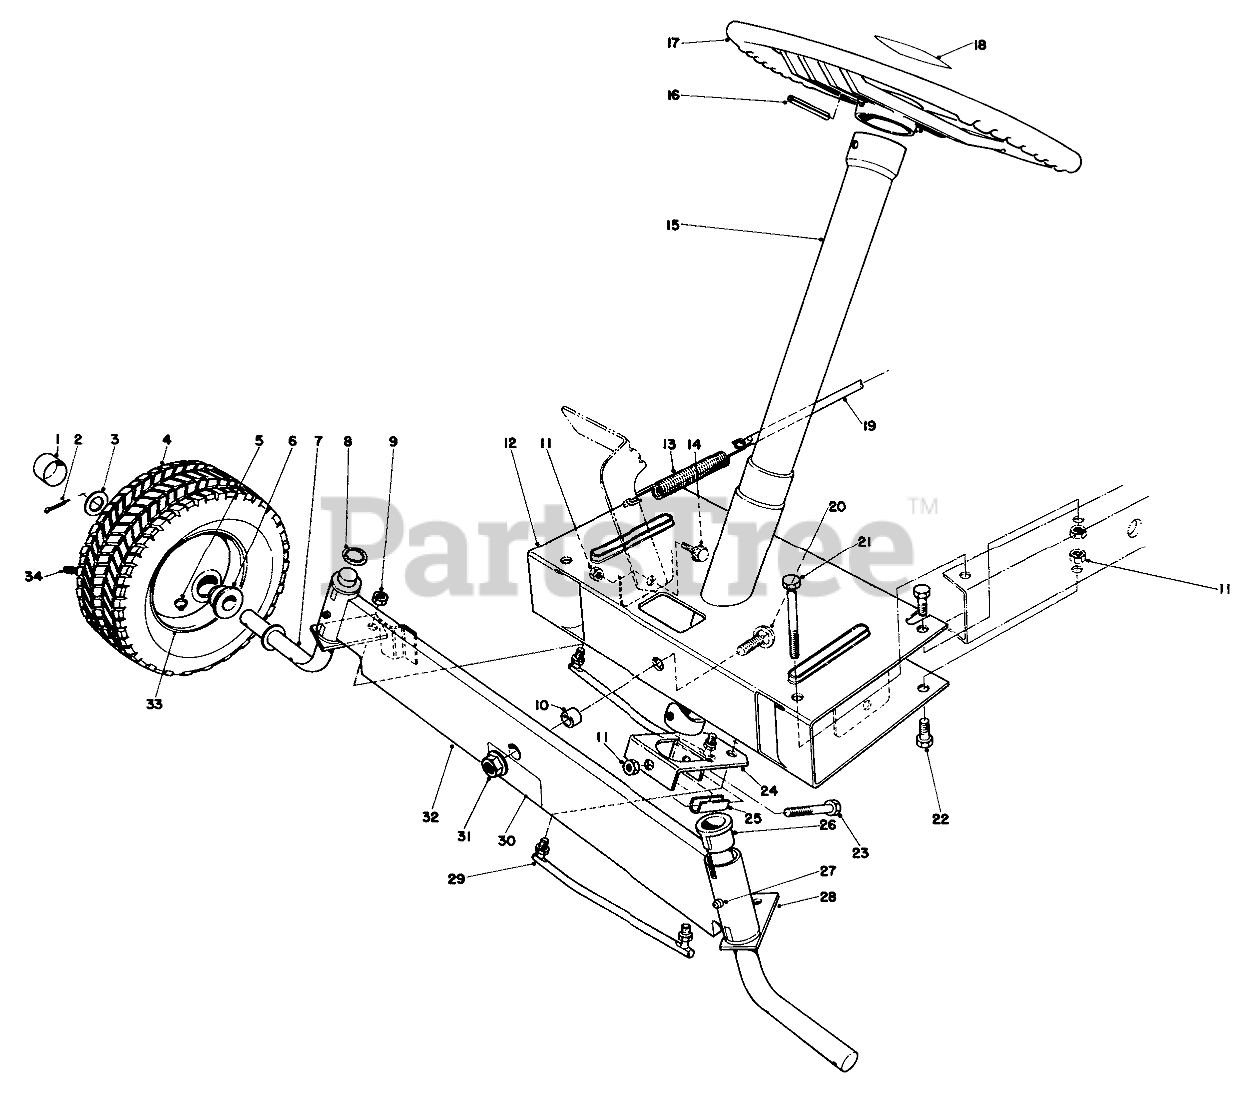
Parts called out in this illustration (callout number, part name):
1	Hub Cap
2	PIN-COTTER
3	WASHER-FLAT
4	Tire Turf King
5	FITTING-GREASE
6	BUSHING
7	SPINDLE WA RH
8	RING-RETAINING
10	FRONT AXLE SPACER
11	NUT-LOCK, CONE
12	Front Frame
13	BRAKE TENSION SPRG O
14	SCREW-SHOULDER
15	Steering Tube
16	PIN-ROLL
17	Steering Wheel
18	Decal
19	Brake Rod
20	SCREW-CARR
21	SCREW-HH
22	SCREW-HH
23	SCREW-HH
24	Lever Steering
25	Spacer-Steering Tube
26	BUSHING
27	Fitting-Grease
28	Spindle L.H.
29	TIE ROD ASM
30	Decal-Warning
31	NUT-HF
32	Front Axle
34	STEM-VALVE
